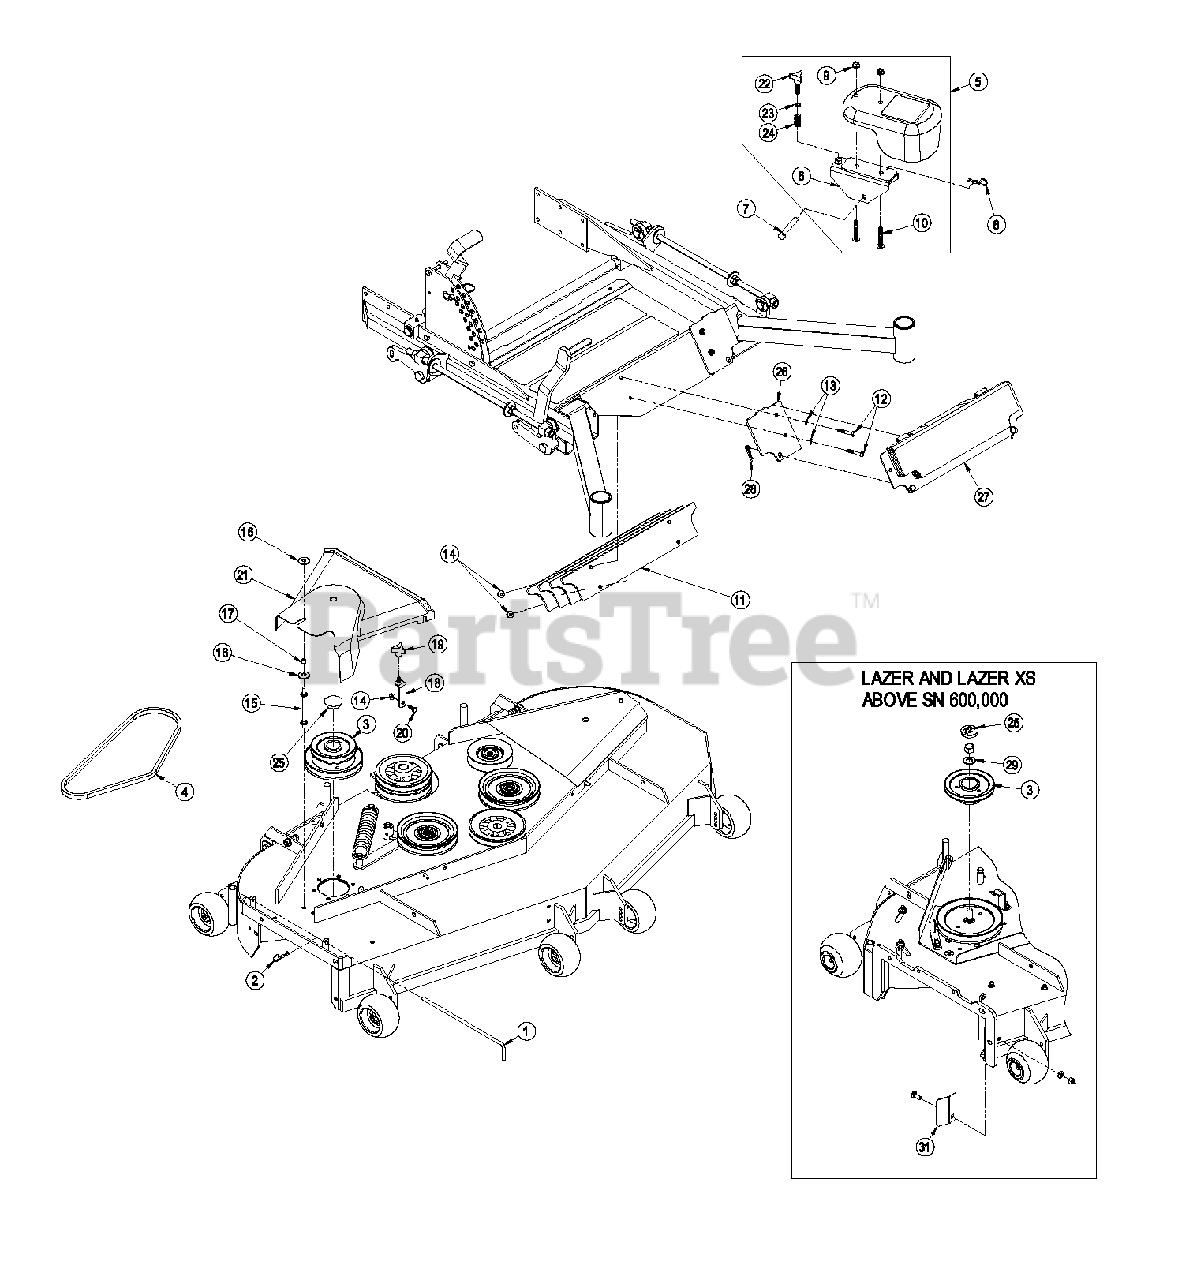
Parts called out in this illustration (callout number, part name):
1	PIN,CHUTE PIVOT
2	PIN-COTTER
3	Sheave 66 Triton
4	BELT, BLOWER DRIVE 72
5	ASM, WEIGHT 2.0" 43 POUND
6	WLD, BRACKET 2.0 ARM
7	PIN-CLEVIS
8	PIN-COTTER
9	NUT-HHF, WHIZ
10	BOLT-SQH
11	Plate, Weight
13	Washer, 5/16 SAE
15	STUD,BELT SHIELD 4 INCH
17	Spacer, Grommet
18	Support, Belt Cover
19	Knob
21	COVER, BELT 66
23	WASHER-FLAT
25	PLUG, BLACK NYLON 1.75
26	Plate, Weight Mounting
27	Asm, Weight Plate W/Decals
28	Hairpin, Cotter
29	WASHER-FLAT
31	DEFLECTOR,LZ UV
